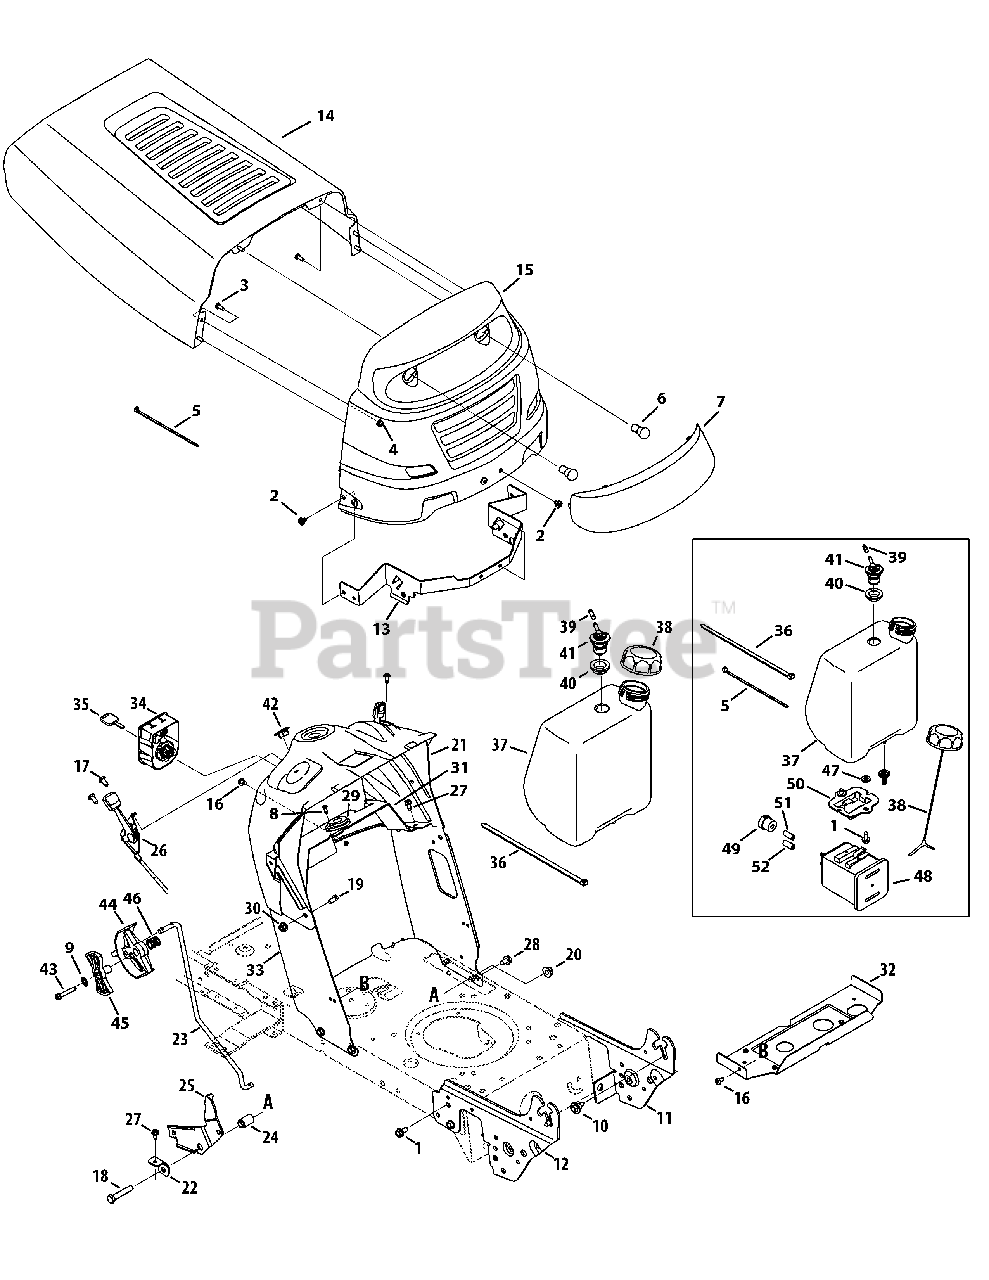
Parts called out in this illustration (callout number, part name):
1	Screw 5/16-18 x .750
2	Screw, 5/16-18 x .375
3	Hex Screw, 1/4-20 x .620
4	Flangelock Nut, 1/4-20
5	Cable Tie
6	Miniature Lamp 12V Socket
7	Lens Grill
8	Screw, #10-16 x .500
9	Lock Washer, 1/4
10	Shoulder Screw .43 x .29
11	Suppport Bracket LH
12	Suppport Bracket RH
13	Hood Pivot Bracket
14	Hood - Red
14	Hood - Gray
15	Grill - Red
15	Grill - Gray
16	Screw, 1/4-20 x .500
17	Screw 1/4-20 x .500
18	Hex Screw 3/8-16 x 2.00
19	Hex Screw, 5/16-18 x .625
20	Flange Lock Nut 3/8-16
21	Dash, Upper
22	Speed Latch Tab
23	Speed Control Rod
24	Flange Spacer .39 x .671 x 1.095
25	Transmission Speed Latch
26	Throttle/Choke Control Cable
27	Tap Screw, 1/4-20, 0.625
28	Screw 5/16-18 x .625
29	Bearing, .628 ID x 1.36
30	Flange lock Nut 5/16-18
31	Bracket, Steering Support
32	Gas Tank Support Bracket
33	Dash, Lower Powder Black
33	Dash, Lower Black Jack
34	Key Switch Module
36	Cable Tie
37	Fuel Tank, 1.36 Gallon
38	Fuel Cap
38	Fuel Cap, 2.25" EPA
39	Hose Vent, 3/16
40	Rubber Grommet
41	Rollover Valve
42	Choke Plug
43	Hex Washer Screw, 1/4-20 x 1.50
44	Shift Lever
45	Index Control
46	Compr. Spring, .72 OD x .78
47	Flat Washer, .344 x .750 x .120
48	5 Gallon Carbon Canister
49	Vent Filter Canister
50	Canister Adapter Bracket
51	Fuel Hose, White
52	Fuel Hose, Yellow
